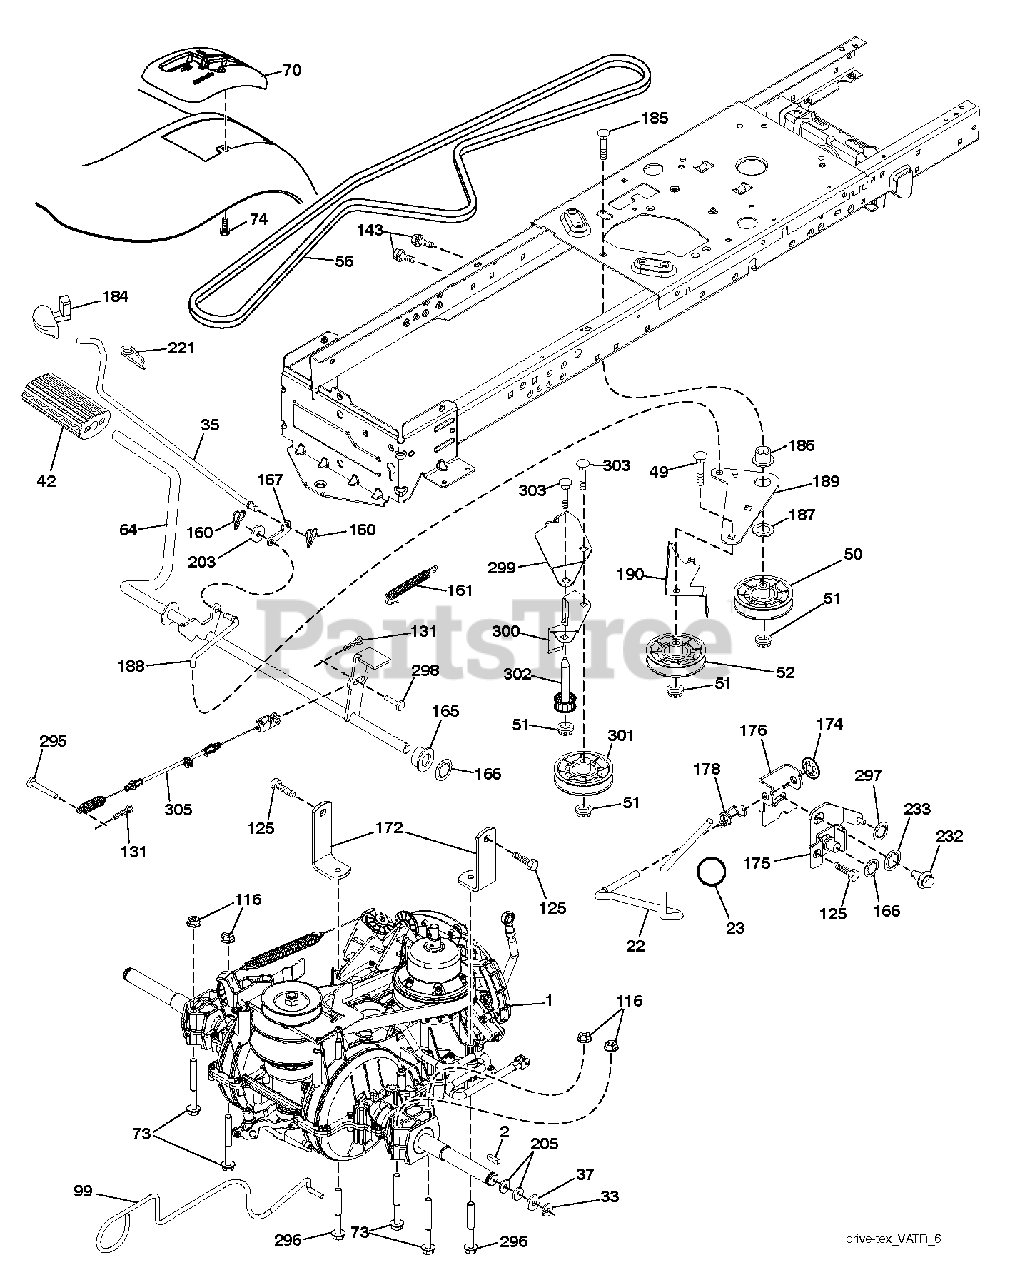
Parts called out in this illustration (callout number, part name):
2	SQUARE KEY
22	ROD.SHIFT.LT.TEX.VARIATOR
23	KNOB.DELUXE.(PISTOL.GRIP).BLAC
35	ROD.BRAKE.PARTK.HUSQ.TEX
42	PEDAL COVER T
50	IDLER.FLAT.910.OFFSET
51	NUT LOCK FLG 3/8-16 UNC
52	IDLER.V-GROOVE.910.OFFSET
56	BELT.DRIVE.MOWER.TEX.42"
64	SHAFT.ASM.PEDAL.BRAKE.
70	CONSOLE.AUTO.VARIATOR.GRY.TEX
73	BOLT HEX 5/16-18 GR 5
74	SCREW.HI-LO.CONSOLE
99	ROD.BYPASS.VARIATOR
116	NUT LOCK HEX FLANGE 5/16-18
125	SCREW
131	COTTER PIN
143	SCREW LT
160	RETAINER CLIP
161	SPRING, RETURN LT
165	BUSHING.SHAFT.BRAKE.HAND
166	NUT.PUSH.625
167	LATCH.BRAKE.SPRING
172	STRAP.TORQUE.VARIATOR
174	NUT.PUSH.500.2006
175	SHAFT.ASM.SHFT.T2.TLT
176	ARM.CLEVIS.ROD.SHIFT
178	SPRING.SHIFT.GT2006
184	RB HANDLE.PARKG.BRK.HUS/PRED
186	SPACER.RETAINER
187	WASHER 12/32X2X10GA
188	RP LINK.CLUTCH.GROUND.DRIVE
189	BELLCRANK.GROUND.DRIVE.TEX.
190	KEEPER.BELLCRANK.DRIVE
203	WASHER
221	RETAINER.SPRING.CLIP.H
232	BOLT FIN HEX 7/16-14 X 1
233	WASHER SERRATED
295	PIN.CLEVIS.183
296	SCREW.THDROL.5/16-18
297	PIN.CLEVIS.CBL.BRK.VARIATOR.TX
298	PIN.CLEVIS.CBL.BRK.VARIATOR.TX
299	BRACKET.MOUNT.IDLERS
300	PULLEY.IDLER.V-GROOVE
301	PULLEY.IDLER.V-GROOVE
302	RB PULLEY.IDLER.FLAT.2.0"OD RP
303	BOLT CARRIAGE
305	CABLE.BRAKE.VARIATOR.TEX
